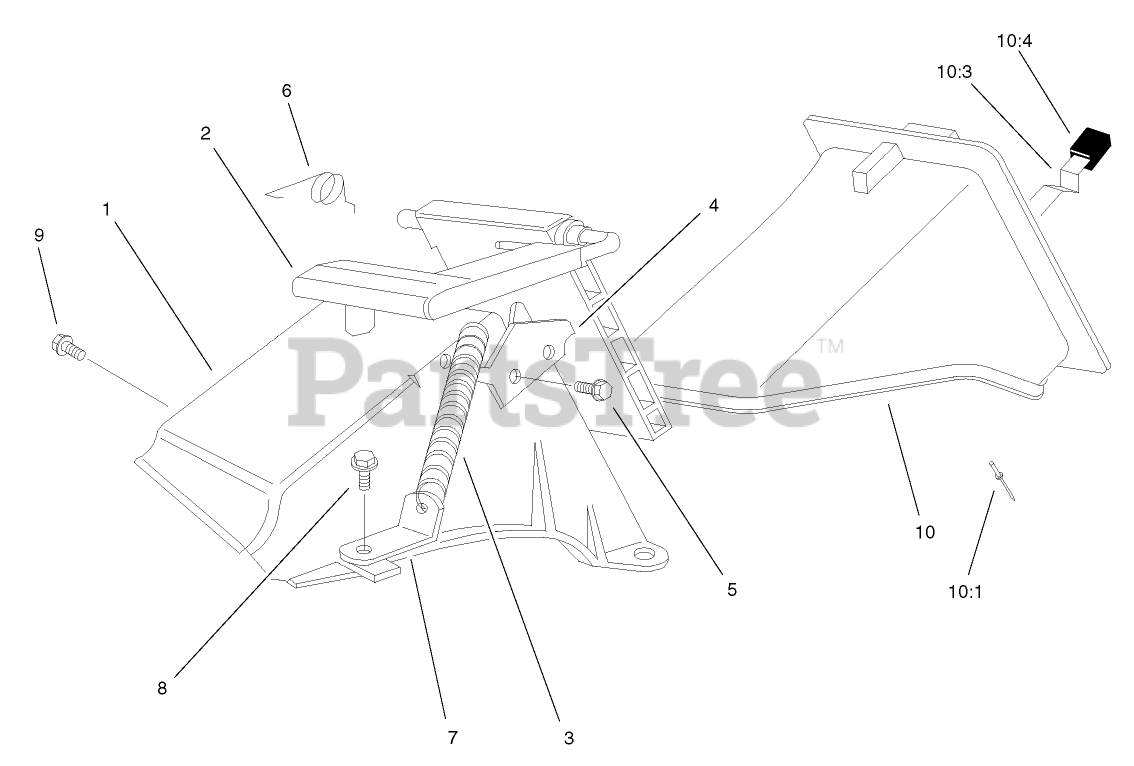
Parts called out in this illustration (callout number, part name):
1	TUNNEL-DISCHARGE
2	DISCHARGE DOOR ASM
3	SPRING-DOOR
4	LATCH-PLATE
5	SCREW-PLASTITE
6	RETAINER-DOOR
7	BRACKET-SPRING
8	SCREW-HWH
9	SCREW AND WASHER ASM
10	DISCHARGE PLUG ASM
10:1	RIVET-HEAD, FLAT
10:3	LATCH-PLUG, DISCHARGE
10:4	GRIP-LATCH
